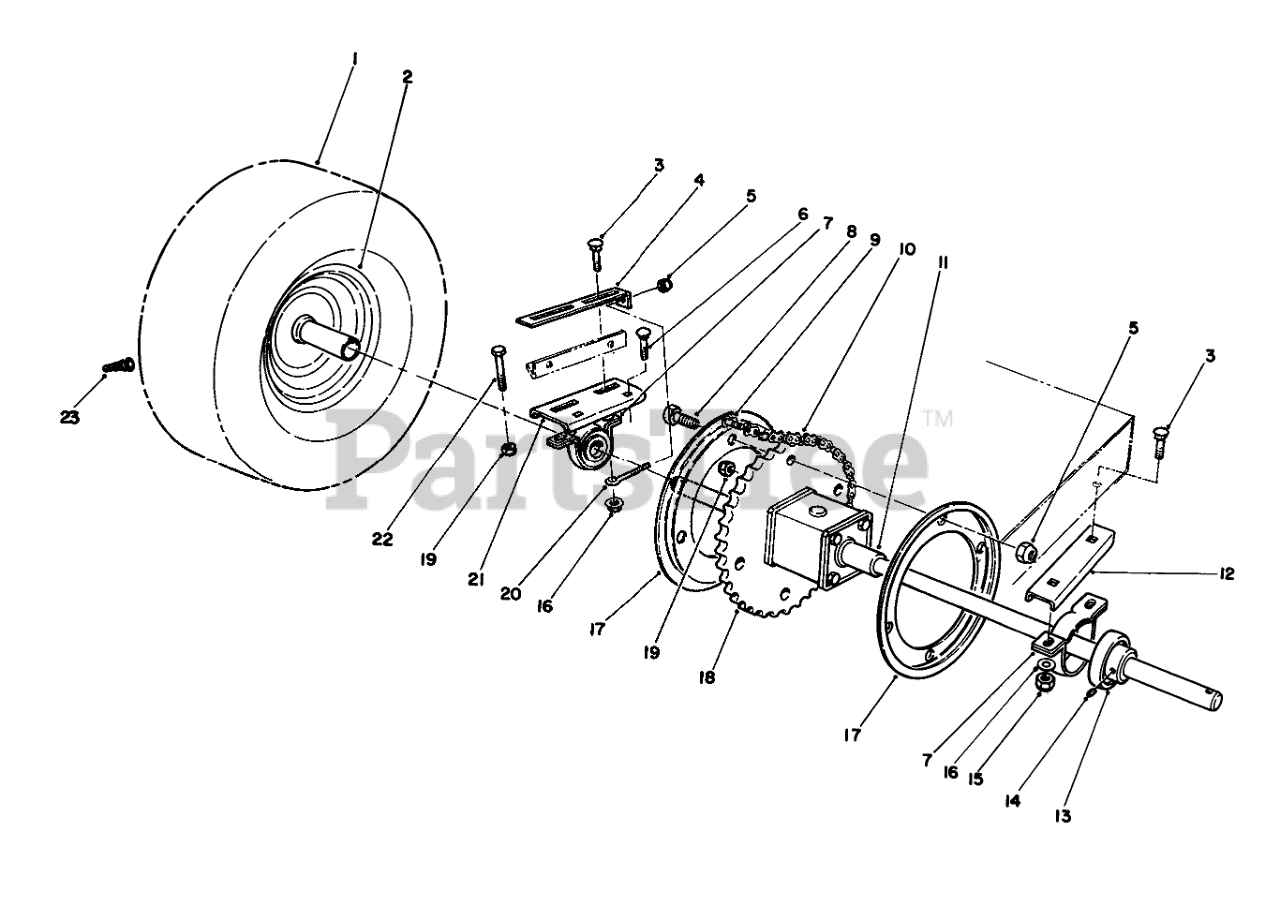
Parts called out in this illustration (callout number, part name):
1	TIRE,PNEU.13X5.00X6
2	WHEEL-REAR
3	SCREW-CARR
4	PLATE-ADJUSTING
5	NUT-LOCK, NI
6	BOLT-CARR
7	RTNR-PILLOW BLK
8	SCREW-HH
9	LINK-CHAIN
10	Chain (Incl. Ref. #9)
11	DIFFERENTIAL
12	Support L.H.
13	Bearing (Incl. Ref. #14)
14	SCREW-HSH
15	NUT-LOCK, NI
16	WASHER-FLAT
17	Guide-Chain
18	SPROCKET
19	NUT-LOCK, NI
20	SCREW-ADJUSTING
21	Support R.H.
22	AXLE MTG BOLT
23	STEM-VALVE
